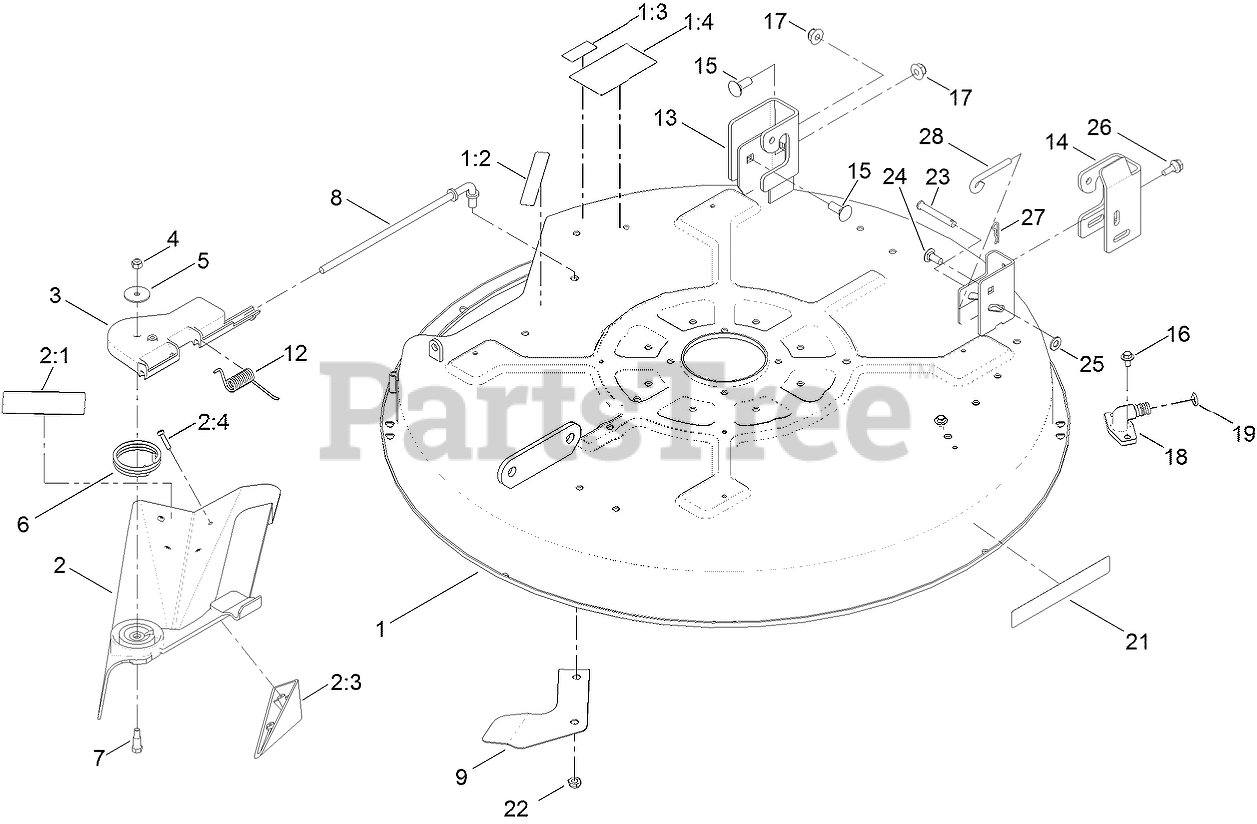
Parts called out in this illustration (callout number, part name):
1	32 INCH DECK AND DECAL ASM
1:2	DECAL-DANGER
1:3	DECAL-DANGER
1:4	DECAL-DANGER
2	32 INCH DEFLECTOR ASM
2:1	DECAL-DANGER
2:3	KICKER
2:4	SCREW-PPH
3	PIVOT-HINGE, DEFLECTOR
4	NUT-LOCK, NI
5	WASHER-FLAT
6	SPRING-TORSION
7	BOLT-SHOULDER
8	ROD-PIVOT
9	RAMP-DEFLECTOR
12	SPRING-TORSION
13	BRACKET-HANGER, RH
14	BRACKET-HANGER, LH
15	BOLT-CARR
16	SCREW-HHFTF
17	NUT-HF, NI
18	FITTING-WASHOUT
19	O-RING
21	DECAL-RECYCLER
22	NUT-LOCK, NI
23	PIN-CLEVIS
24	SCREW-CARR
25	WASHER-PLAIN
26	SCREW-SHOULDER, HHF
27	PIN-COTTER
28	ROD-LEVEL, DECK
